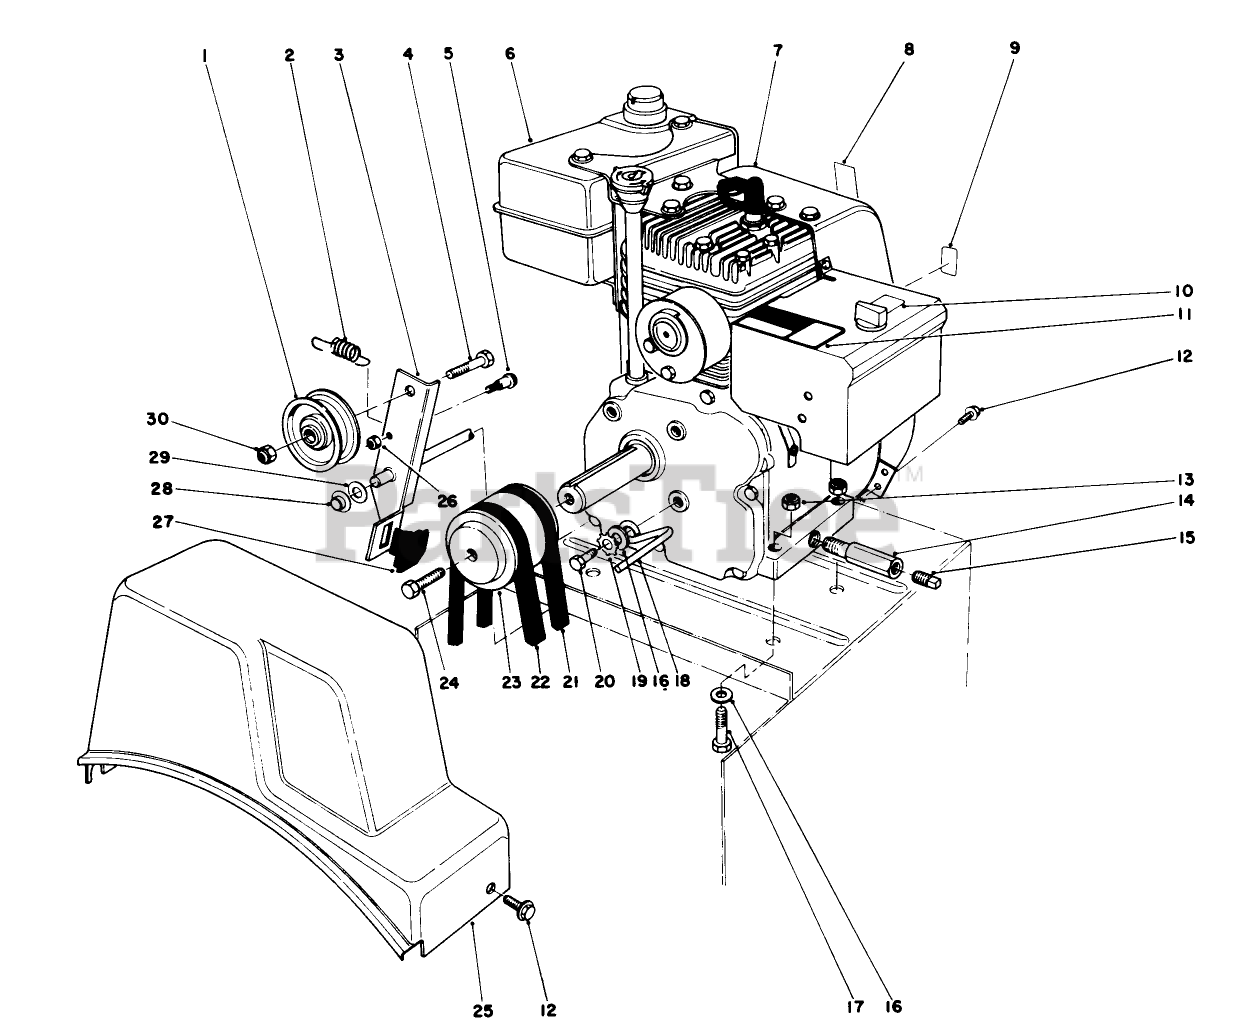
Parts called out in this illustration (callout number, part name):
1	PULLEY-IDLER
2	SPRING
4	SCREW-HH
5	BOLT-SHOULDER
7	Engine
9	THROTTLE DECAL, INT'L
10	CHOKE DECAL
12	SCREW-HWH
13	NUT-LOCK, NI
14	PIPE-NIPPLE
15	CAP-PIPE
16	WASHER-PLAIN
17	SCREW-HH
18	RETAINER-BELT
19	WASHER-LOCK
20	SCREW-HH
21	V BELT-3L, TRACTION
22	V-BELT
23	PULLEY-ENGINE
24	SCREW-SPECIAL
25	COVER-BELT
26	NUT-LOCK, NI
27	PAD-BRAKE
28	NUT-PUSH
29	WASHER-FLAT
